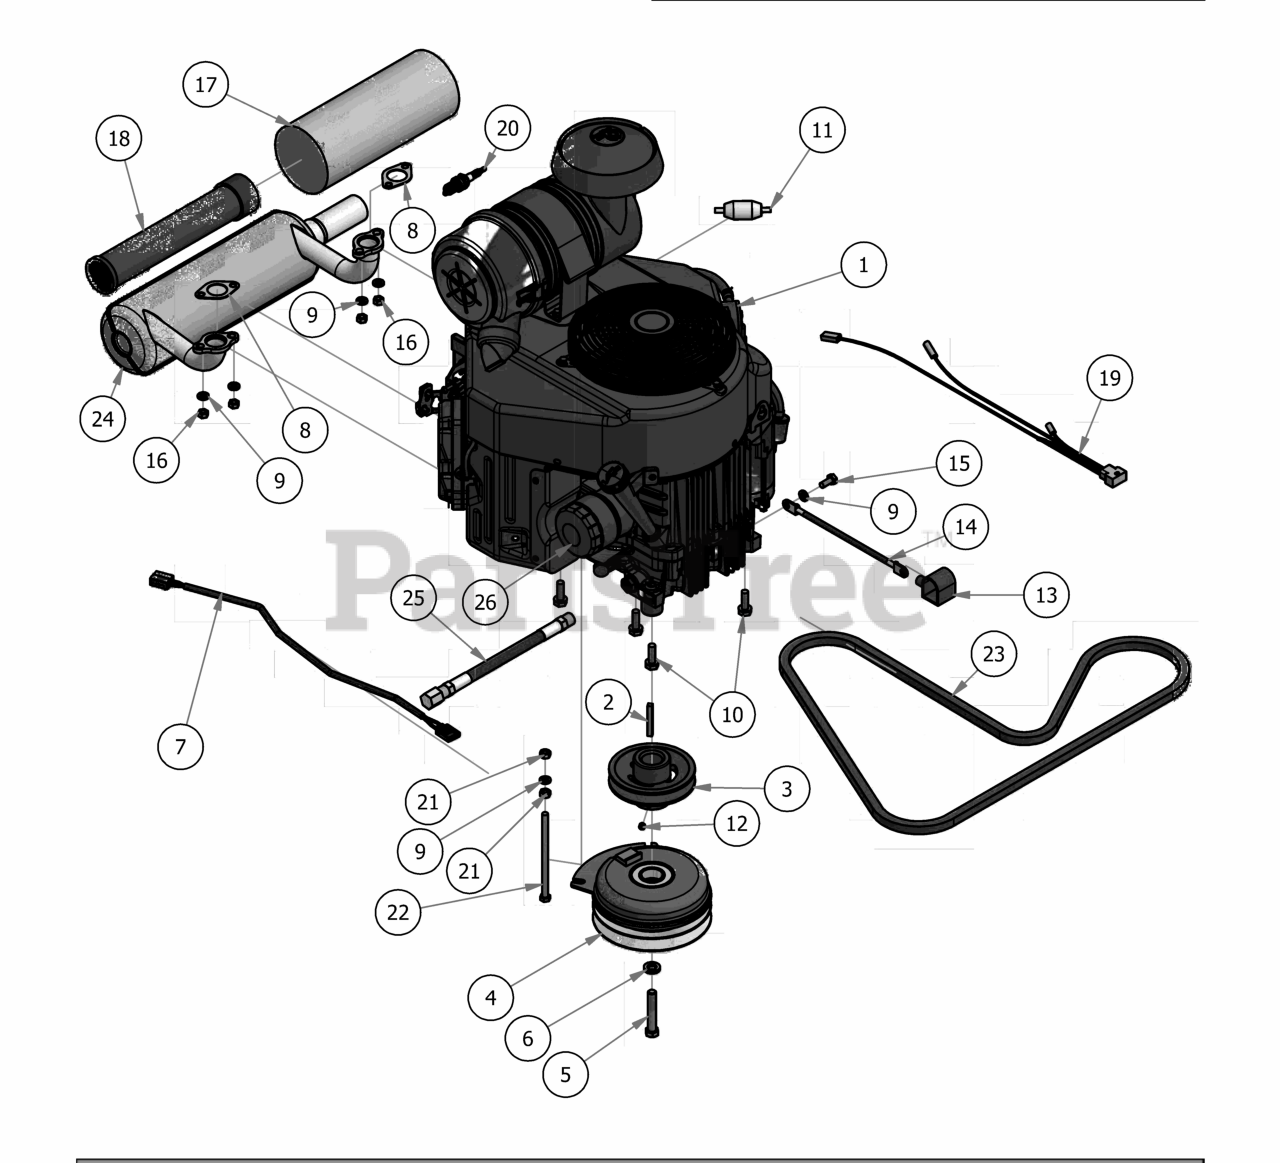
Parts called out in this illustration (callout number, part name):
2	1/4 x 2 Square key Stock
3	4 3/4 Motor Pulley
4	Clutch Assembly
5	7/16" x 2 1/2" Hex Bolt
6	7/16" Lock Washer
7	Clutch Pigtail
8	Exhaust Gasket
9	5/16" Lock Washer
10	3/8 x 1 1/8 bolt
11	Universal Inline Fuel Filter
12	5/16 Set Screw
13	Black Boot For Ground Cable
14	Ground Cable
15	M8x1.20x20MM Hex head bolt
16	M8-1.25 Zinc Nut
17	Canister Air Filter- Outer
18	Canister Air Filter- Inner
19	Harness Adaptor
20	Spark Plug - Kawasaki
22	5/16-18 x 5-1/2 GR 5 Hex Bolt
24	Kawasaki Muffler 1251
25	Oil drain Hose
26	Oil Filter
